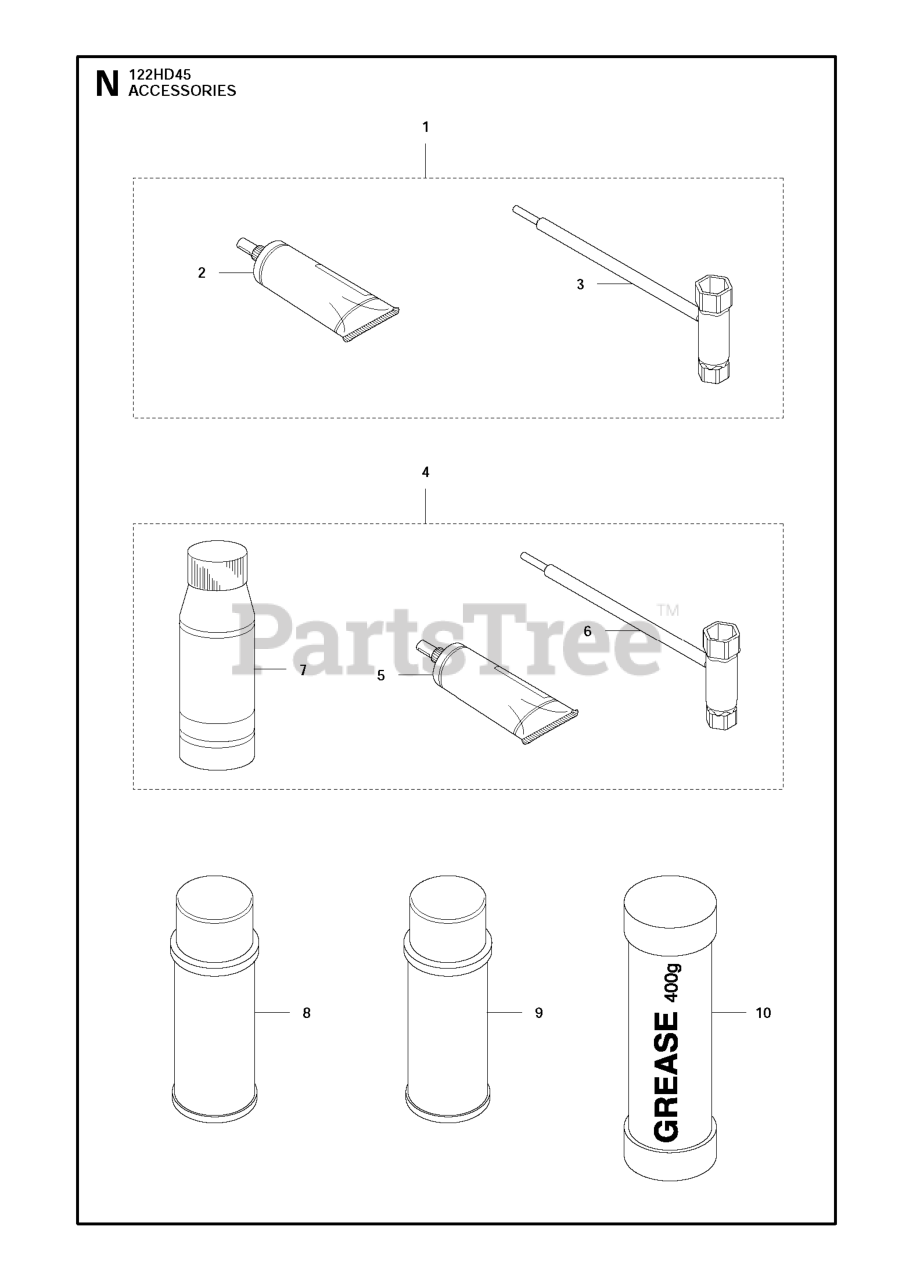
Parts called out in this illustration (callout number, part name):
1	ACCESSORY BAG
2	GREASE TUBE
3	COMBINATION WRENCH
4	ACCESSORY BAG
5	GREASE TUBE
6	COMBINATION WRENCH
7	OIL (BLUE CAP) XP 2.6 OZ
10	HUS MULTI ADVANCE GREASE 400GR
